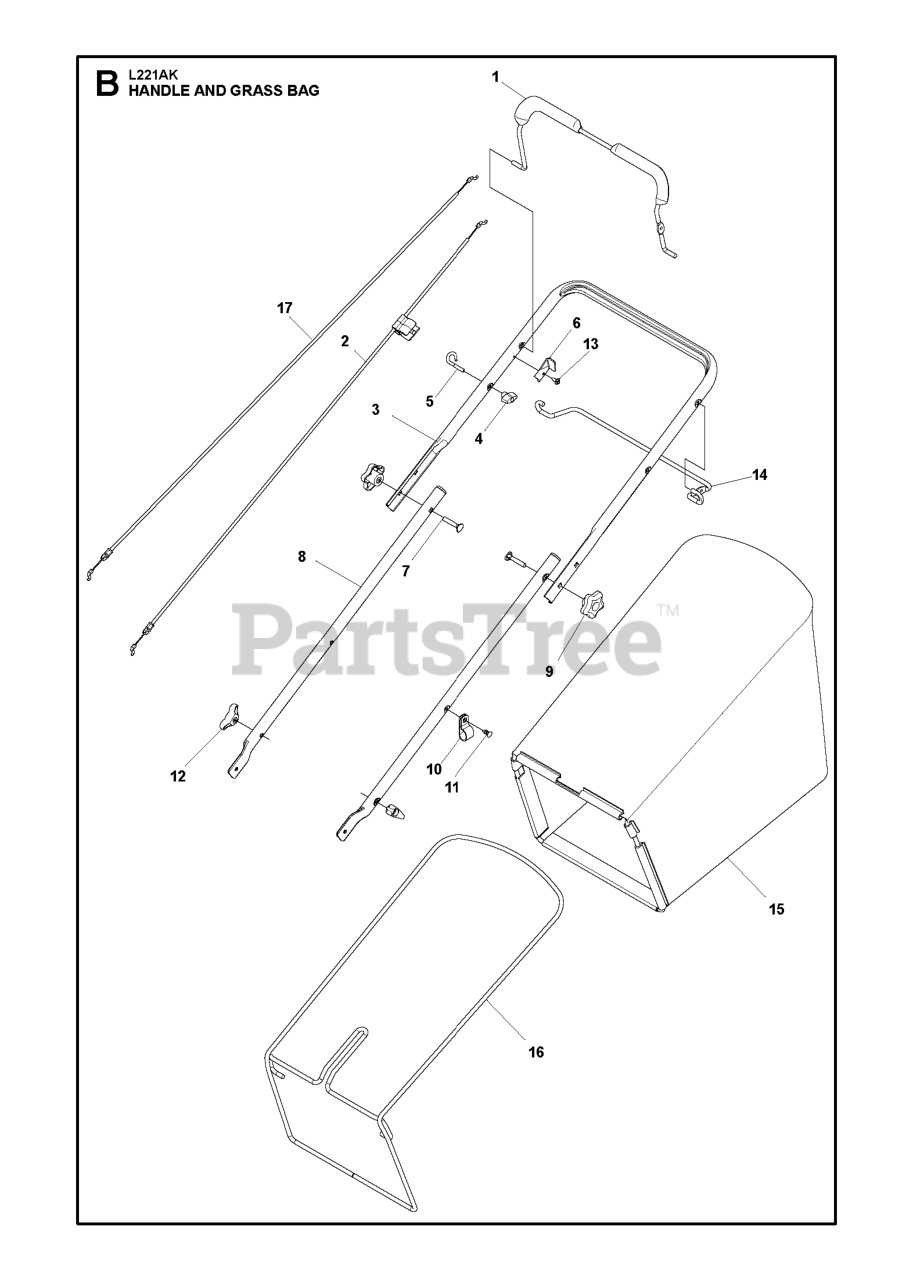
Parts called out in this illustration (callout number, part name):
1	BAIL.ARM.ASSY:STRAIGHT OM
2	CABLE.MZR.DUAL.5.95EXT45.92CON
3	HANDLE.UPP.DST.EXTCR.SM.SP.498
4	T-KNOB.NEW ROPE GUIDE
5	GUIDE.ROPE.BLK.ZINC.CHROM
6	BRACKET.UPSTOP.RT
7	BOLT.CONCAVE.HEAD.RETAINING
8	HANDLEBAR ASSY TWO PIECE LOWER
9	KNOB.HANDLE.PLASTIC.STAR.BLACK
10	CLIP.CABLE.BLK
11	FASTENER.PUSH.O.250X0.783
12	KNOB, DEFLECTOR
13	SCREW
15	GBAG.C361029EM.HUSQ.GRY.21EFF
16	FRAME.GBAG.AWD.21.BLACK
17	CABLE.DRIVE.UB.NA.21EFF.AW
